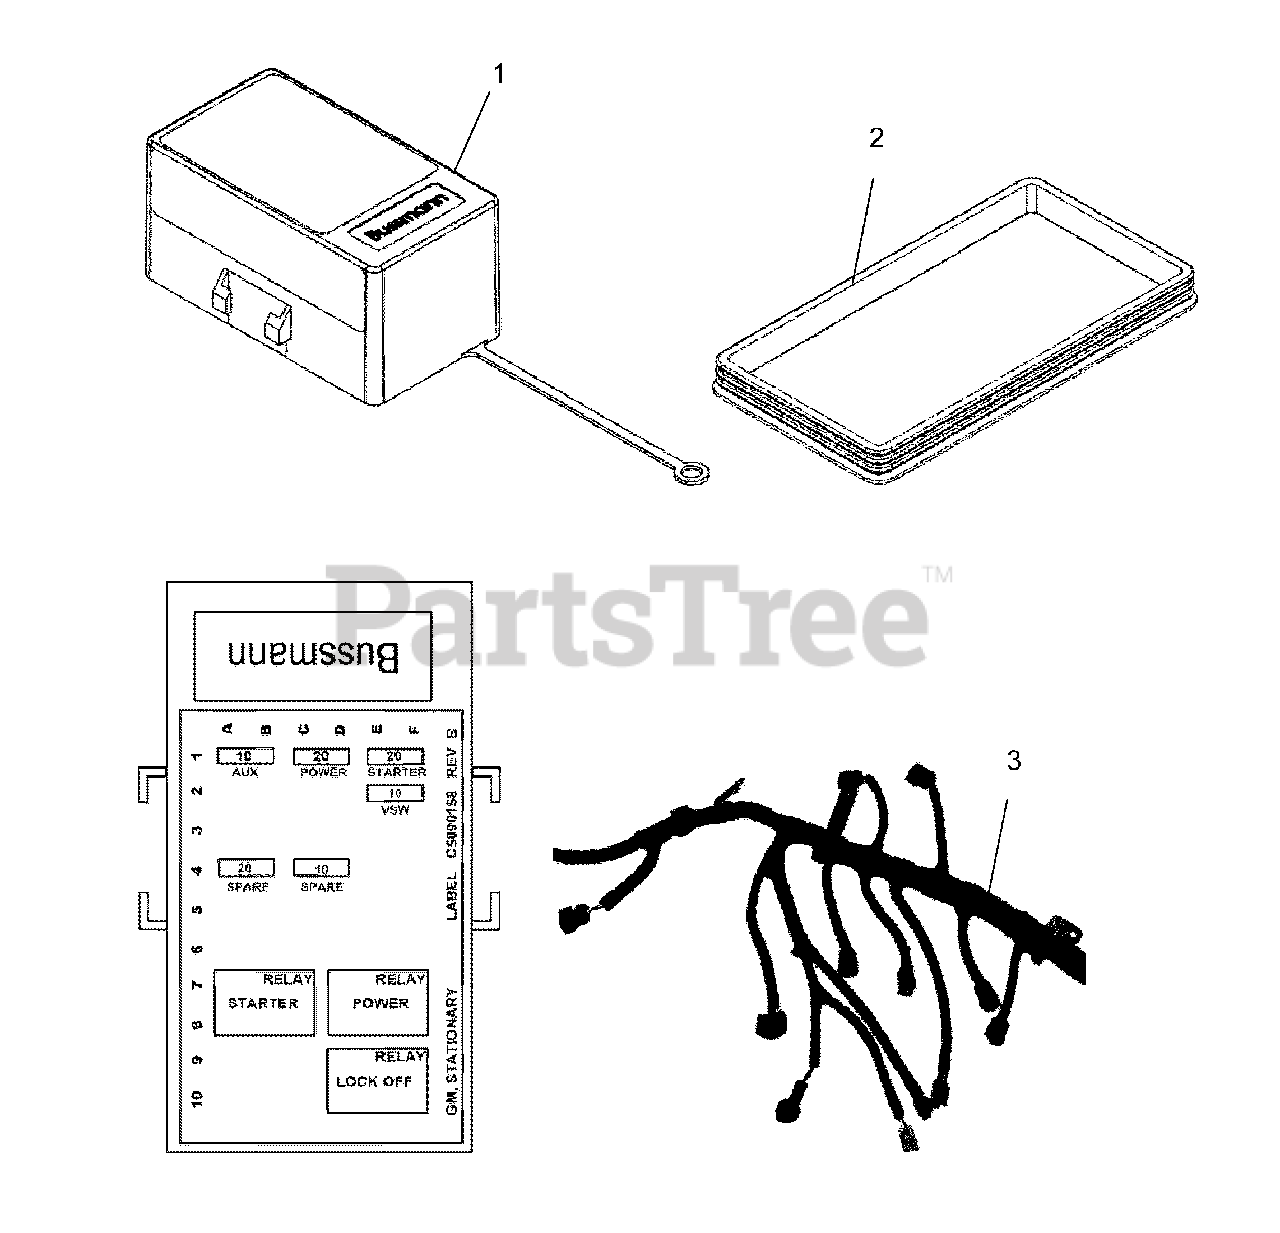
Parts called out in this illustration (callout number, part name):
1	COVER
2	SEAL-FUSE BOX
3	HARNESS-WIRE GENSET
